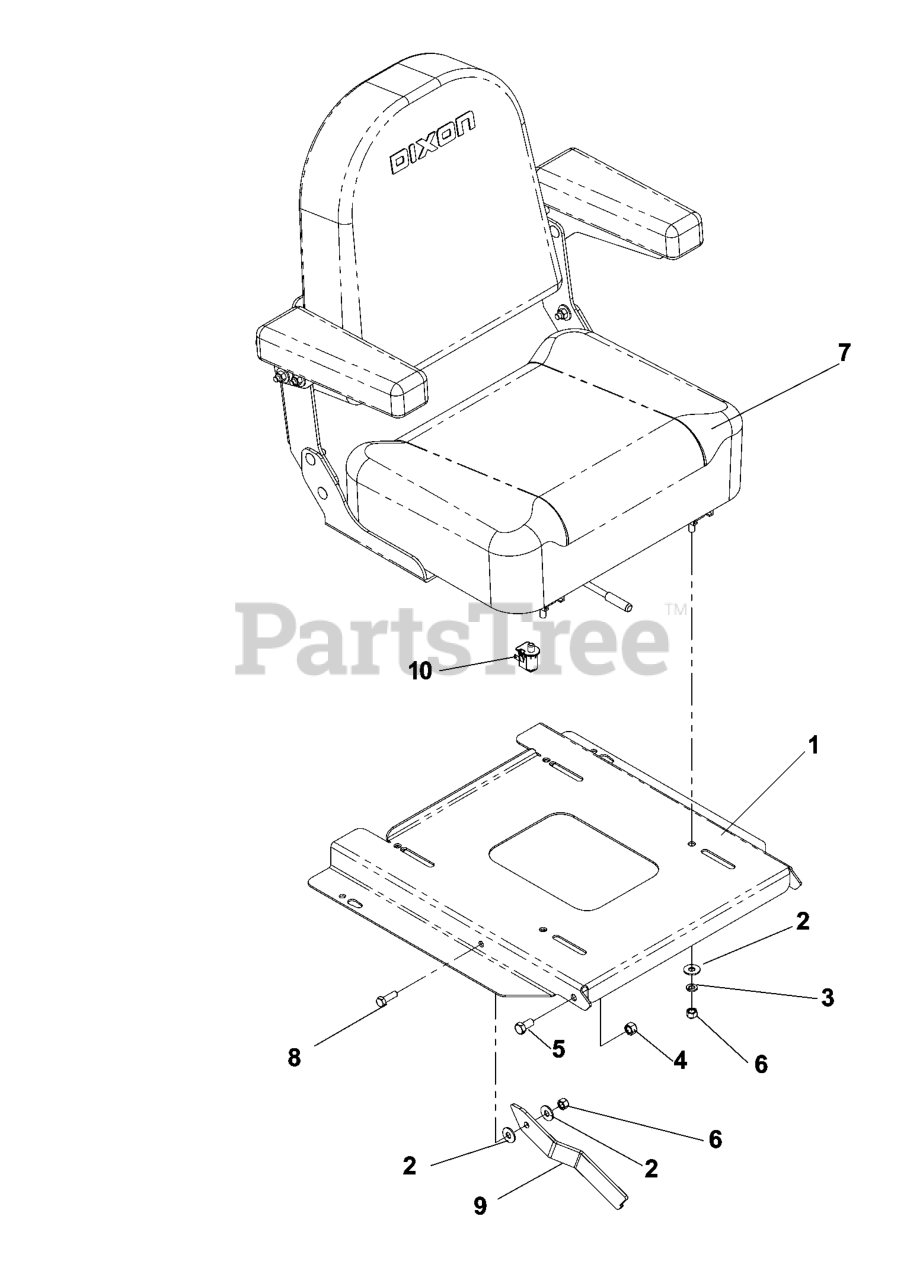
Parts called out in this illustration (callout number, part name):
1	PAN, SEAT
2	WASHER 5/16 FLAT
3	WASHER 5/16 LOCK
4	NUT 3/8-16 NYLOC
5	SCREW 3/8C X 3/4 HEX CAP
6	NUT 5/16 NYLOC
7	SEAT ASM W/SLIDE
8	HCS 5/16C X 1
9	ARM, PROP, SEAT
10	SEAT SWITCH
